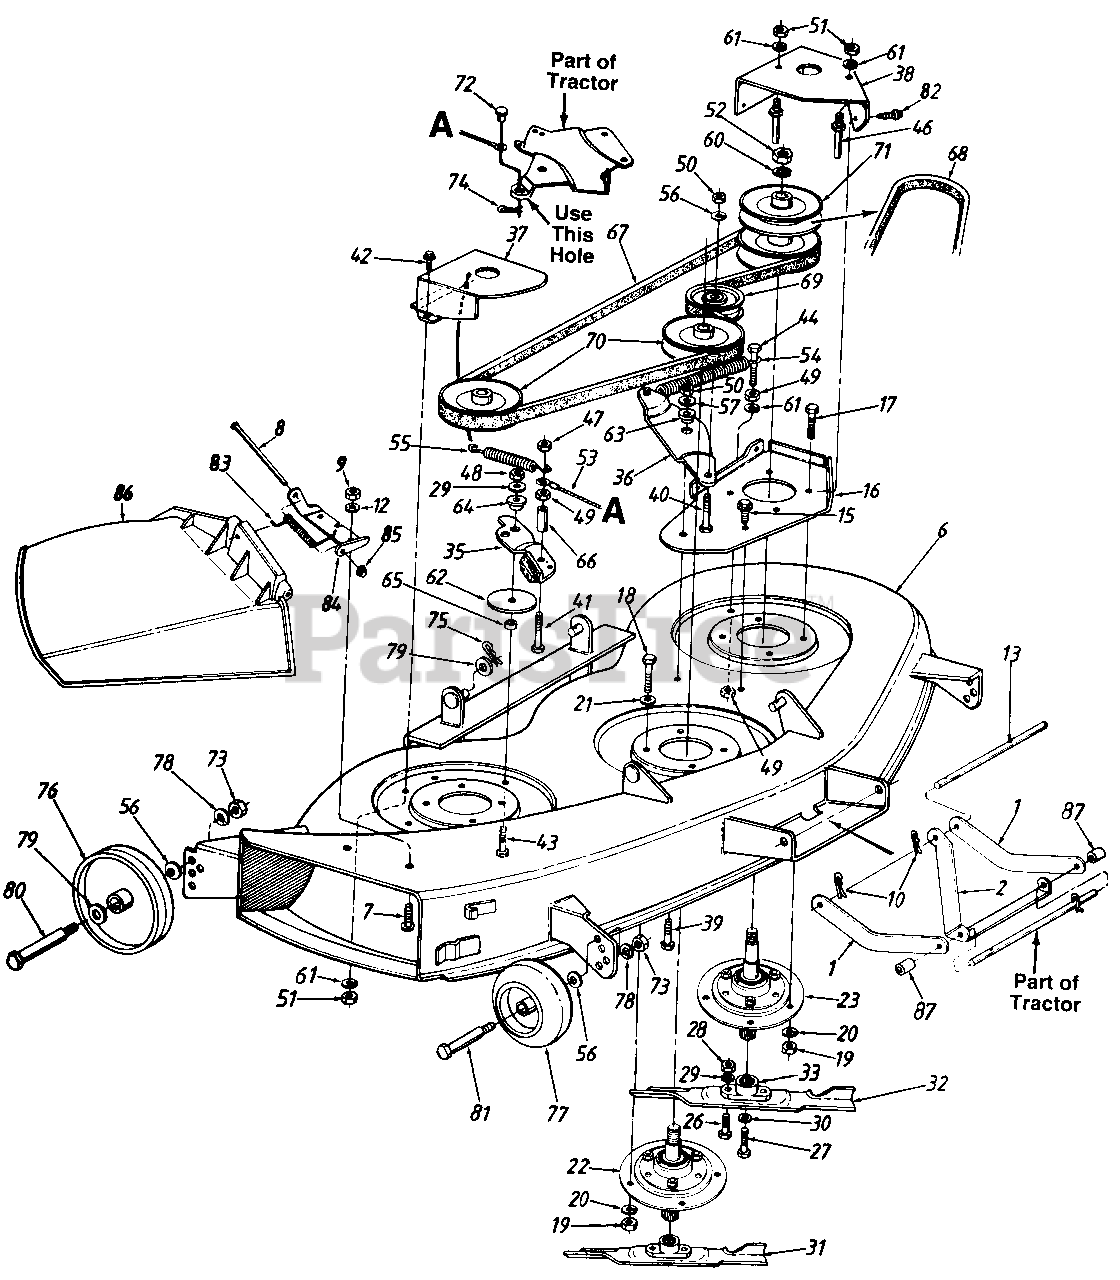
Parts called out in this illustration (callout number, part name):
7	Hex Bolt 1/4-20 x .62" Lg.
8	Hinge Pin
9	Hex Jam Nut 1/4-20 Thd.
12	Bell-Wash. 1/4" I.D.
13	Deck Connecting Rod
15	Hex TT-Tap Scr. 5/16-18 x .62"
18	Hex Bolt 5/16-24 x .75" Lg.
19	Hex Nut 5/16-24 Thd.
20	L-Wash. 5/16" I.D.
21	Bell-Wash. 5/16" I.D.
22	Spindle Ass'y. (R.H. & Center)
23	Spindle Ass'y. (L.H.)
26	Hex Bolt 5/16-24 x 1.0" Lg. (Spec.)
27	Hex Cl-Bolt 3/8-24 x .88" Lg.
28	Hex Nut 5/16-24 Thd.
29	L-Wash. 5/16" I.D.
30	L-Wash. 3/8" I.D. - H.D.
31	High Lift Blade 14.88" Lg.
32	High Lift Blade 16.28" Lg.
33	Blade Adapter
35	Deck Brake Brkt. Ass'y.
36	Idler Bracket
40	Hex Bolt 3/8-24 x 1.5" Lg.
41	Hex Bolt 1/4-28 x 1.75" Lg.
42	Hex Wash. Hd. Tap-Scr. 1/4-20 x .5" Lg.
43	Hex Bolt 5/16-24 x 1.5" Lg. (Grade 5)
44	Hex Bolt 1/4-28 x 1.5" Lg.
46	Belt Guard Pin 1/4" Dia.
47	Hex Cent. L-Nut 1/4-28 Thd.
48	Hex Nut 5/16-24 Thd.
49	Hex Nut 1/4-28 Thd.
50	Hex Nut 3/8-24 Thd.
51	Hex Nut 1/4-20 Thd.
52	Hex Jam Nut 5/8-18 Thd.
53	Brake Cable Ass'y.
54	Extension Spring 6.17" Lg.
55	Extension Spring 3.97" Lg.
56	Bell-Wash. .38" I.D. x .88" O.D.
57	Bell-Wash. .39" I.D. x 1.13" O.D.
60	L-Wash. 5/8" I.D.
61	L-Wash. 1/4" I.D.
62	Fl-Wash. 5/16" I.D. x 3" O.D.
63	Shld. Spacer .625" I.D.
64	Shld. Spacer
65	Spacer .34" I.D.
66	Spacer .326" I.D.
67	V-Belt
68	V-Belt
69	Fl-Idler w/Flanges 3.5" O.D.
70	Pulley 5.0" Dia.
71	Pulley 5.0" Dia.
72	Clevis Pin 1/4" Dia. x .53" Lg.
73	Hex Nut 3/8-16 Thd.
74	Intern. Cotter Pin 5/16" Dia.
75	Intern. Cotter Pin 3/8 Dia.
76	Deck Wheel 5" Dia.
77	Deck Wheel w/Insert 5" Dia.
78	L-Wash. 3/8" I.D."
79	Fl-Wash. .531" I.D.
80	Shoulder Bolt .498" Dia. x 1.64" Lg.
81	Shoulder Bolt
82	Hex Wash. Hd. Tap-Scr. 1/4-20 x .38" Lg.
83	Torsion Spring
84	Hinge Mtg. Brkt.
86	Chute Ass'y. Comp.
87	Spacer 5/8" I.D. x 7/8" O.D.
17258-0648	Deck Belt Cover, 46" Black - TECH GRAY (0648)
17258-0665	COVER:BELT:DECK 46 - YARDMAN GREEN (0665)
